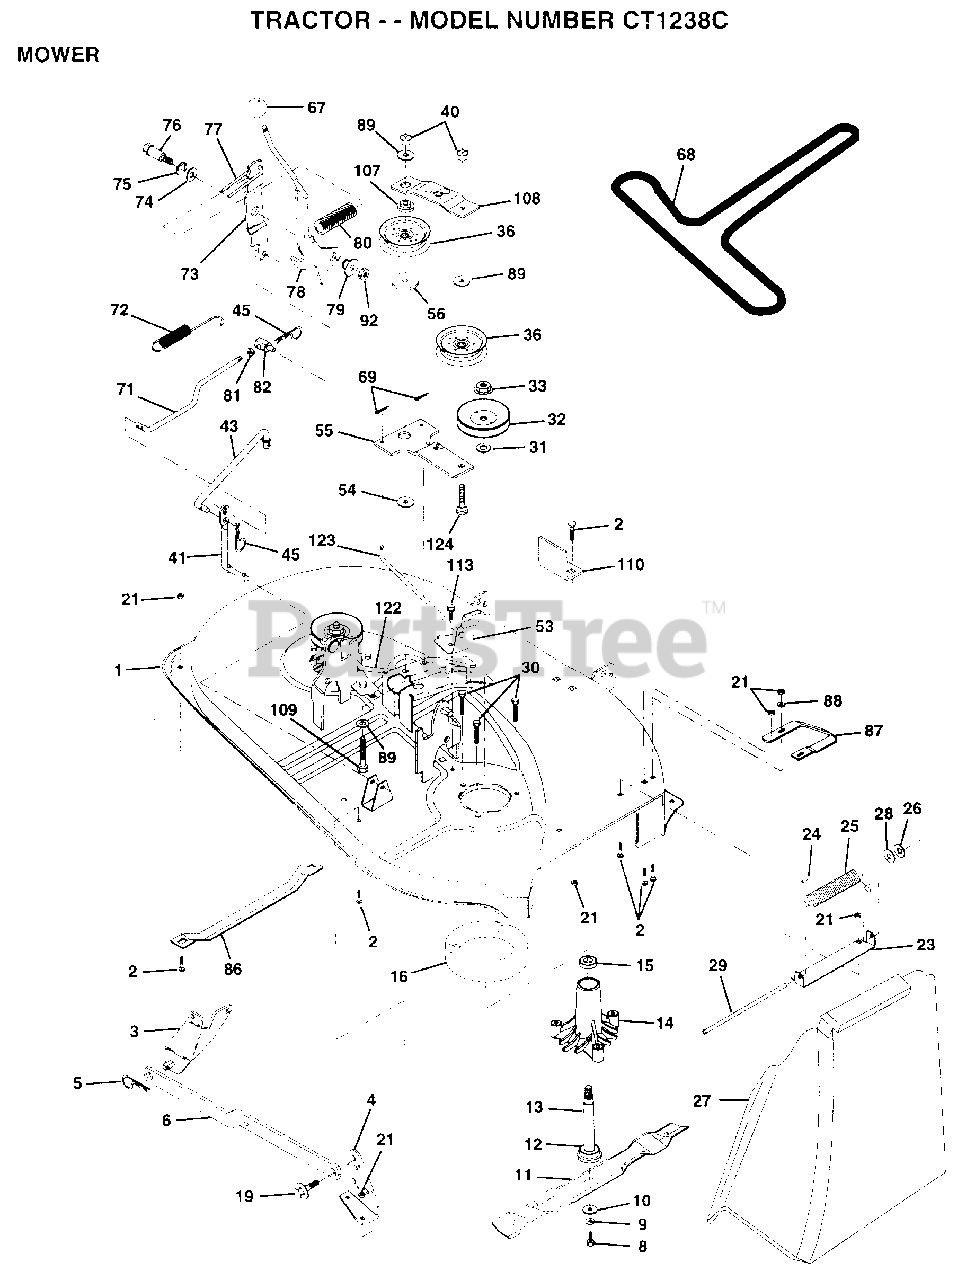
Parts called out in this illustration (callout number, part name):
2	BOLT
3	BRKT ASM SWAY BAR
4	BRKT DECK SW BAR
8	BLADE BOLT
10	WASHER.HARD.BLADE
11	"BLADE.38"" HIPERF"
12	BEARING.BALL
14	HSG ASM MANDREL
15	BEARING
16	STRIPPER RND MWR
19	BOLT SHD 5/16-18
23	BRKT DEFLECTOR
24	CAP-SLEEVE LT
25	SPRING TORSION
26	NUT PUSH M
27	DEFLECTOR-SHLD T
28	WASHER
29	ROD-HINGE T
31	WASHER
36	FLAT IDLER PULLEY
41	PIVOT ROD
43	CLUTCH ROD SECOND
45	RETAINER M
53	BRAKE ASM
54	HARDENED WASHER
55	IDLER ARM ASSY
56	SPACER RETAINER
67	KNOB T(3/8 HOLE)
68	BELT.V.T-PATH
71	ROD CLUTCH 38/42
72	RETURN SPRING
73	CLUTCH ARM SECOND
74	WASHER
75	RING
76	SHOULDER BOLT
77	SPRING KEEPER
79	BUSHING
81	NUT
82	TRUNION ADJ
86	RUNNER-LH M
87	RUNNER RH
88	WASHER M
89	WASHER GT
92	NUT
107	RETAINER SPACER
108	IDLER ARM STIFF
109	BOLT
110	UPSTOP DECK FT 38
113	SCREW
122	BRAKE ROD LH
123	BRAKE ROD RH
124	BOLT
